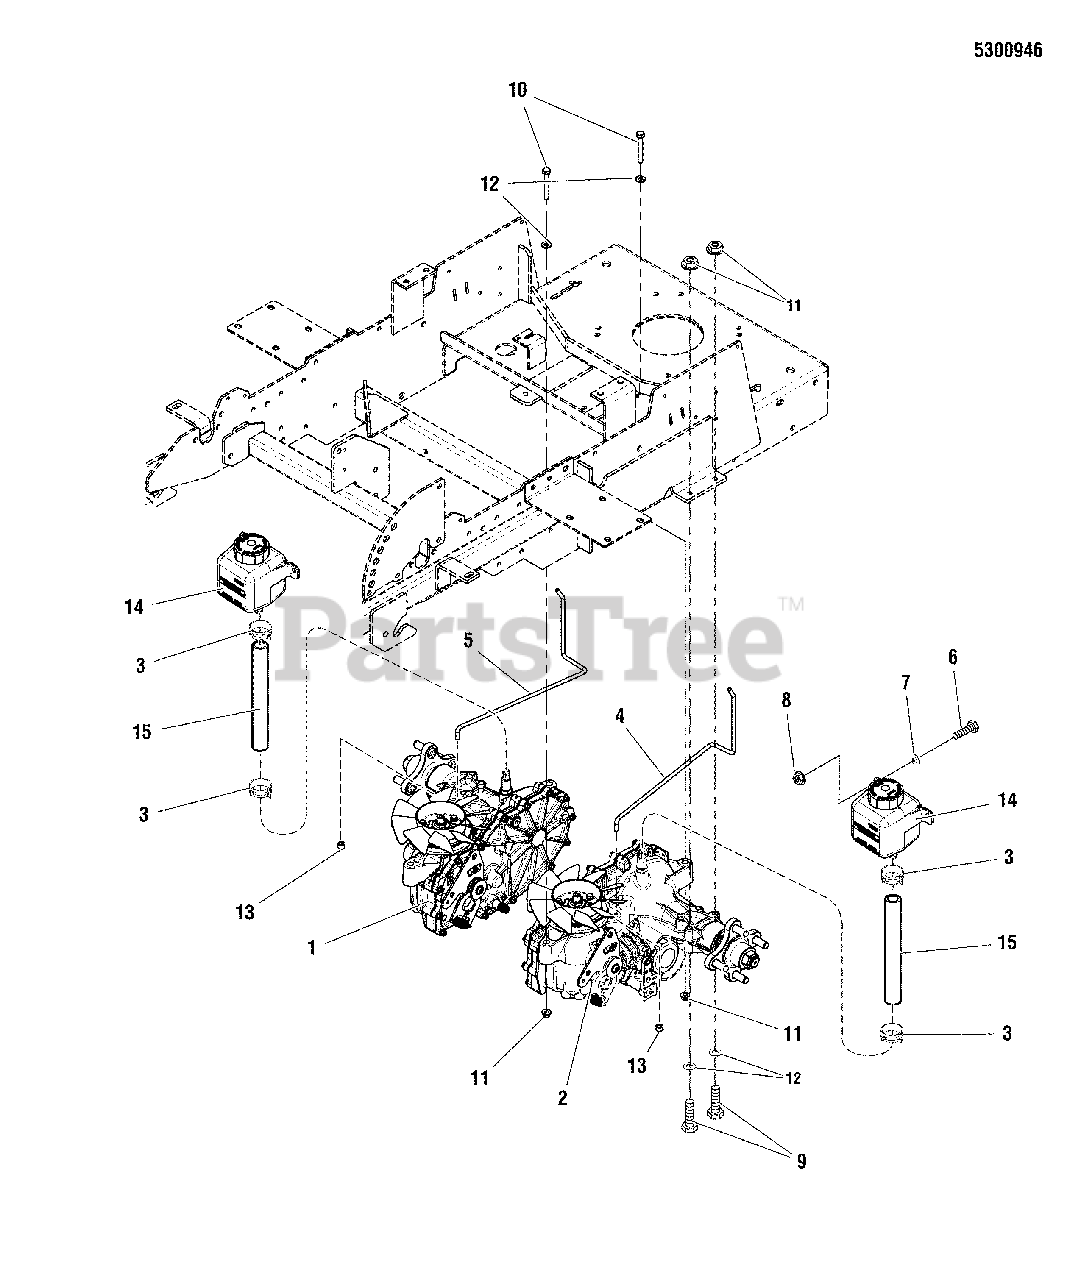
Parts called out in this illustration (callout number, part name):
3	CLAMP, HOSE, 1/2
4	ROD, DUMP VALVE, LH - CONZ
5	ROD, DUMP VALVE, RH - CONZ
6	BOLT, 1/4-20 X 3/4 GD5 YZ
7	WASHER, 1/4 SAE
8	NUT, 1/4-20 HEX NYLOCK FLANGE
9	BOLT, 5/16-18 X 3" GD5 YZ
10	BOLT, 5/16-18 X 2-1/4" GD5 YZ
11	NUT, 5/16-18 HEX NYLOCK FLANGE
12	WASHER, 5/16" SAE
13	COLLAR, 5/16" SET
14	RESERVOIR, HYDRO OIL, 350 ML
15	HOSE, 1/2" PUSH-ON, 9.00"
